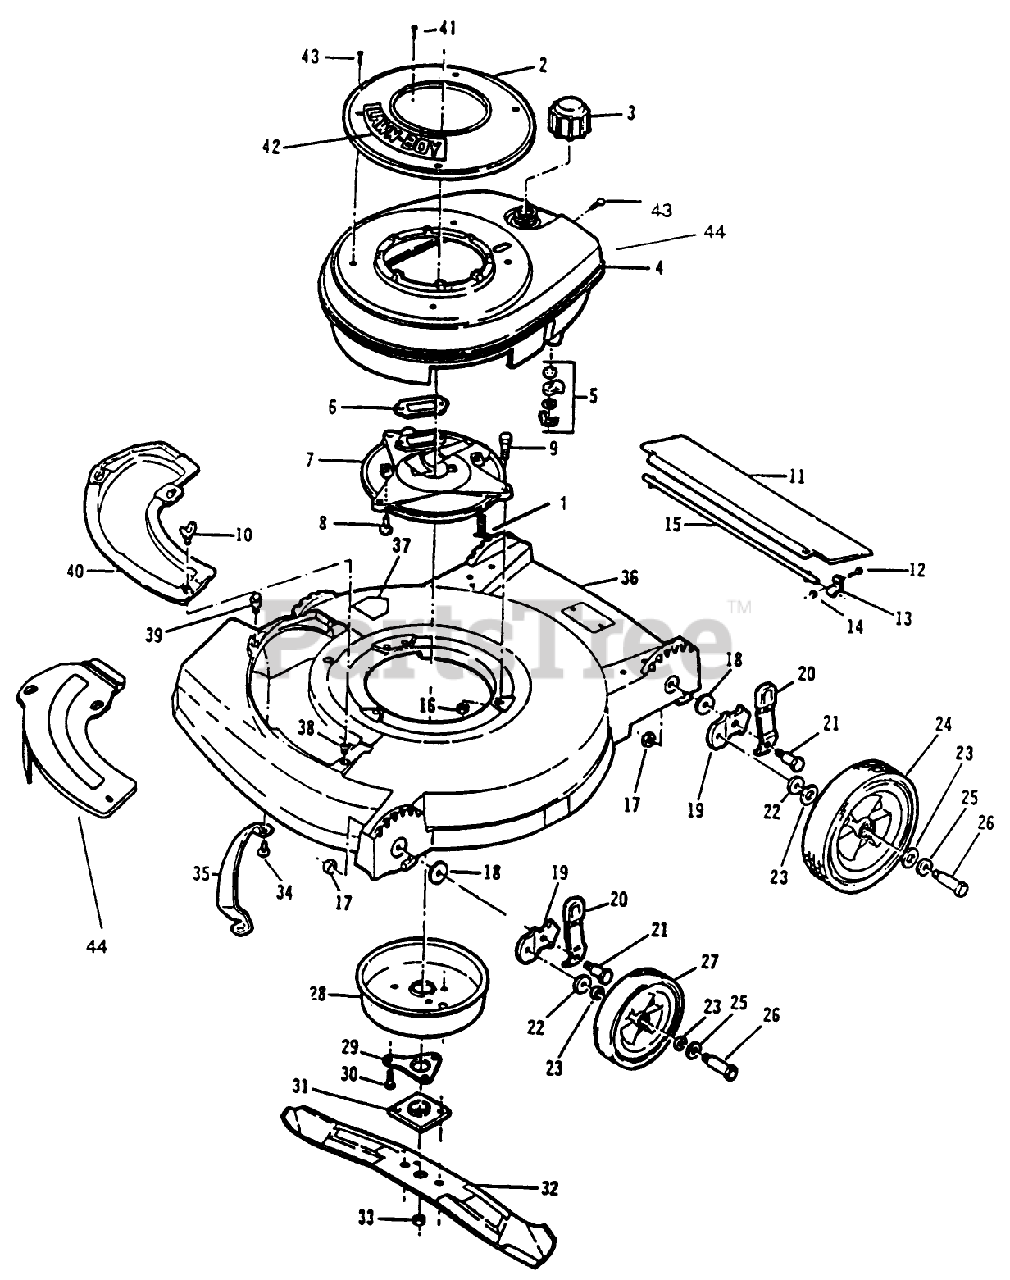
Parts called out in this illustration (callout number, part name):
1	SCREW-SEMS F
2	STARTER BASE&NUT*B
3	FUEL CAP & INSERT
4	SHROUD,TANK&VAL
5	SHUT OFF VALVE KIT
7	PLATE F
8	SCREW V
9	SCREW-HH
10	WING SCREW LAWRE
13	CLAMP ROD KMC
14	LOCKNUT E
15	ROD T/SHIELD ADV WIRE
16	NUT-LOCK F
17	LOCKNUT
18	WASHER
20	SPRING ARM ASM
21	BOLT
22	WASHER WROUGHT
23	WASHER
25	SPACER
26	BOLT WHEEL
27	WHEEL & TIRE KIT
28	MUFFLER COVER F
29	SUPPORT F
30	SCREW
31	PLATE AND COLLAR ASM
33	NUT-BLADE
35	TOE BAR 19"
41	SCREW SEMS SM
43	SCREW - SELF TAPPING
44	Mulch Plate Accessory
